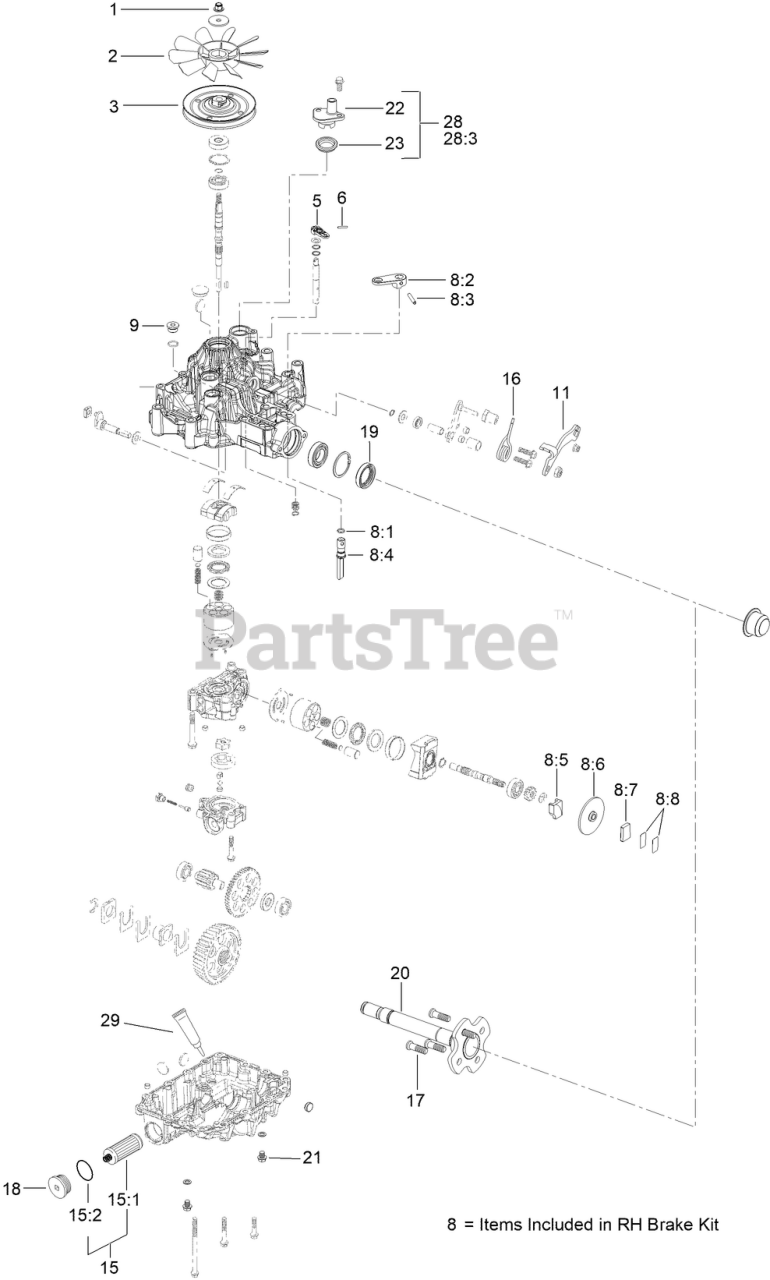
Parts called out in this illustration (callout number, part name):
1	NUT-LOCK
3	PULLEY
6	LEVER-BYPASS
8	RH BRAKE KIT
8:1	O-RING
8:2	ARM-BRAKE
8:3	Pin-Roll
8:4	SHAFT-BRAKE
8:5	ACTUATOR-BRAKE
8:6	DISC-BRAKE
8:7	SHOE-BRAKE
8:8	SHIM KIT
9	CAP-OIL
11	LEVER-CONTROL, RH
15	HYDRO FILTER KIT
15:1	FILTER
15:2	O-RING
16	SPRING-TORSION
17	STUD-WHEEL
18	CAP-OIL FILTER
19	SEAL-AXLE, UA
21	DRAIN BOLT
22	EXPANSION FITTING
23	GROMMET SEAL, EXPANSION FITTING
28	EXPANSION FITTING - W/ SEAL
28:3	M8*20 FLANGE BOLT
29	SEAL KIT
